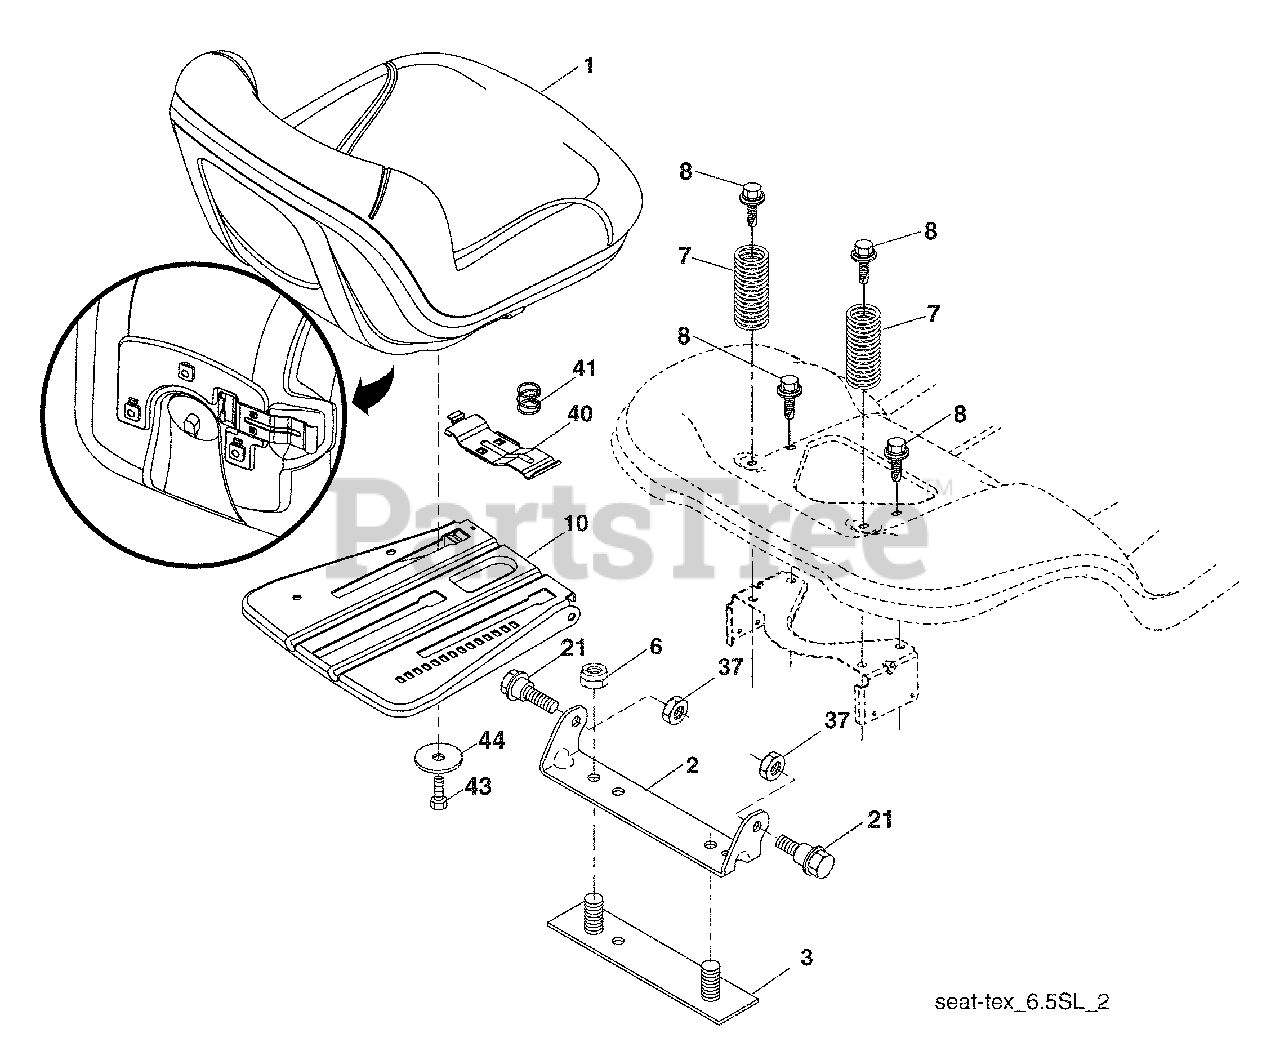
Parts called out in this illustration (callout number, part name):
1	Seat
2	Bracket Pivot Fender
3	Strap, Asm Fender
6	Nut, Lock W/Ins. 3/8-16 unc
7	Spring, Seat Cprsn
8	Bolt 5/16-18 unc x 3/4 w/Sems
10	Pan, Seat
21	Bolt, Shoulder 5/16-18
37	Nut, Lock 5/16-18 unc
40	Handle Slide Seat
41	Spring Latch Seat
43	Bolt Fin Hex 3/8-16 unc x 3/4
44	Washer 13/32 x 2-3/8 x 12 Ga.
